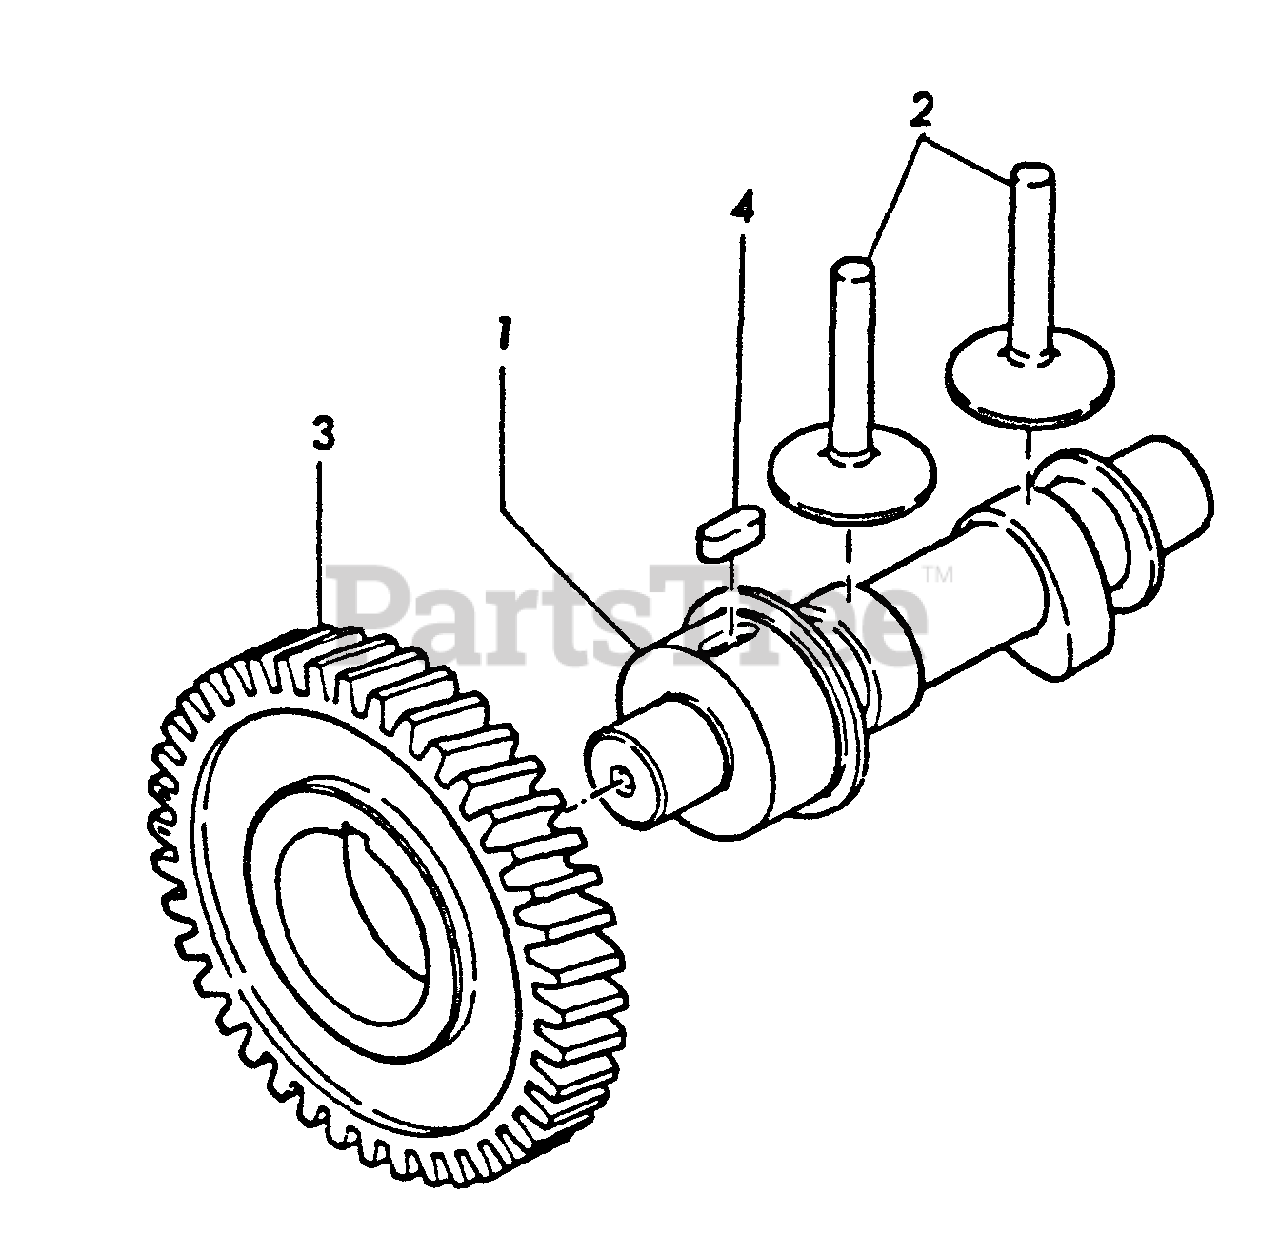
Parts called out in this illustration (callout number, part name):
1	CAMSHAFT
2	TAPPET
3	GEAR, CAMSHAFT
4	KEY 4×12
